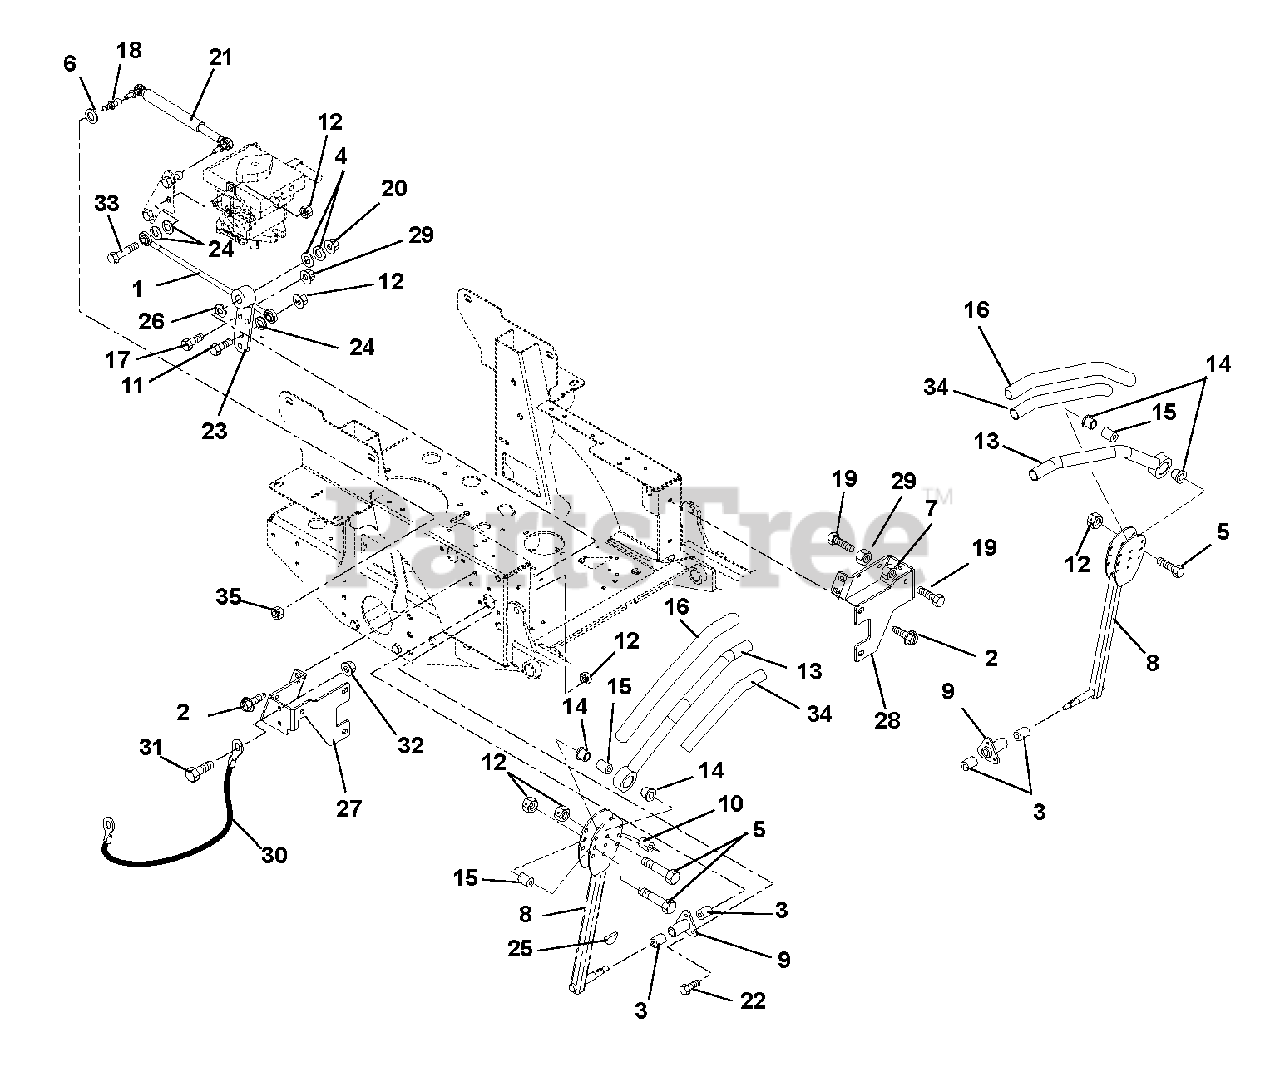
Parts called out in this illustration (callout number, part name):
1	Assembly, Steering Rod
2	Screw, Tapping .38-16 x .75 Hex Washer Head
3	Bushing .625 x .75 x .50
4	Washer, Flat Steel .406 x .812 x .065
5	Bolt, Hex .31-18 x 1.75 Grade 5
6	Washer, Flat Steel .344 x .065 YWZC
7	Nut, Hex Jam .375-16
8	Control Arm
9	Housing, Bushing
10	Bushing, Eccentric .31 x .75 x .97
11	Bolt, Hex .31-18 x 1.25 Grade 5
12	Nut, Nyloc Flange .375-16
13	Handle Weldment, Left Hand
14	Bushing, Flange Nylon .762 x 1.48 x .44
16	Grip, Handlebar
17	Bolt, Hex .375-16 x 1.75
18	Stud, Ball
19	Bolt, Hex .38-16 x 1.25 Grade 5
20	Nut, Nyloc Flange 3/8-16
21	Damper
22	Bolt, Hex .31-18 x 1.00 Grade 5
23	Weldment, Pivot Arm
24	Washer, Locking .31 x .078 Regular
25	Key, Woodruff .13 x .63
26	Wave Washer
27	Stop, Steering, Right Hand
28	Stop, Steering, Left Hand
29	Nut, Locking Jam Center .375-16
30	Cable, Hood
31	Bolt, Hex .25-20 x .75 Grade 5
32	Nut, Nyloc Flange .25-20
33	Bolt, Hex .31-18 x 1.50 Grade 5
34	Tube, .88ID x 1.00OD x 10.75
35	Nut, Top Lock .31-18
